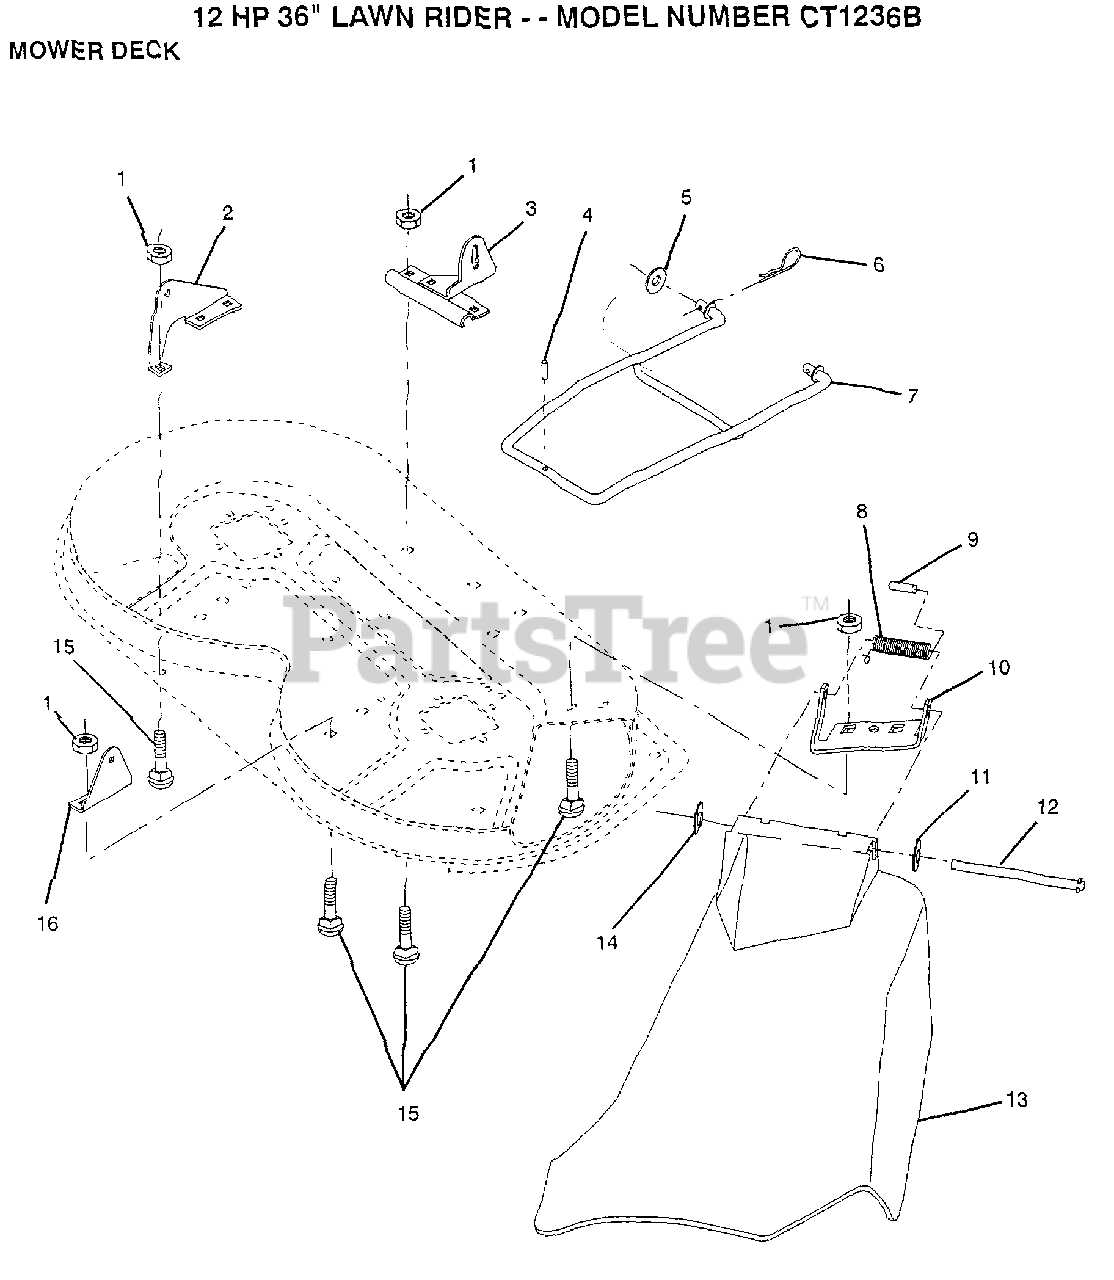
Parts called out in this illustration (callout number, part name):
2	"BRKT,LIFT REAR LH"
3	"BRKT,LINK STABILI"
4	"PIN,GROOVE"
6	RETAINER.SPRING
7	MOWER LINK STAB
8	SPRING TORSION
9	CAP-SLEEVE LT
11	WASHER
12	HINGE ROD
14	NUT PUSH M
15	BOLT
16	"BRKT,LIFT REAR"
